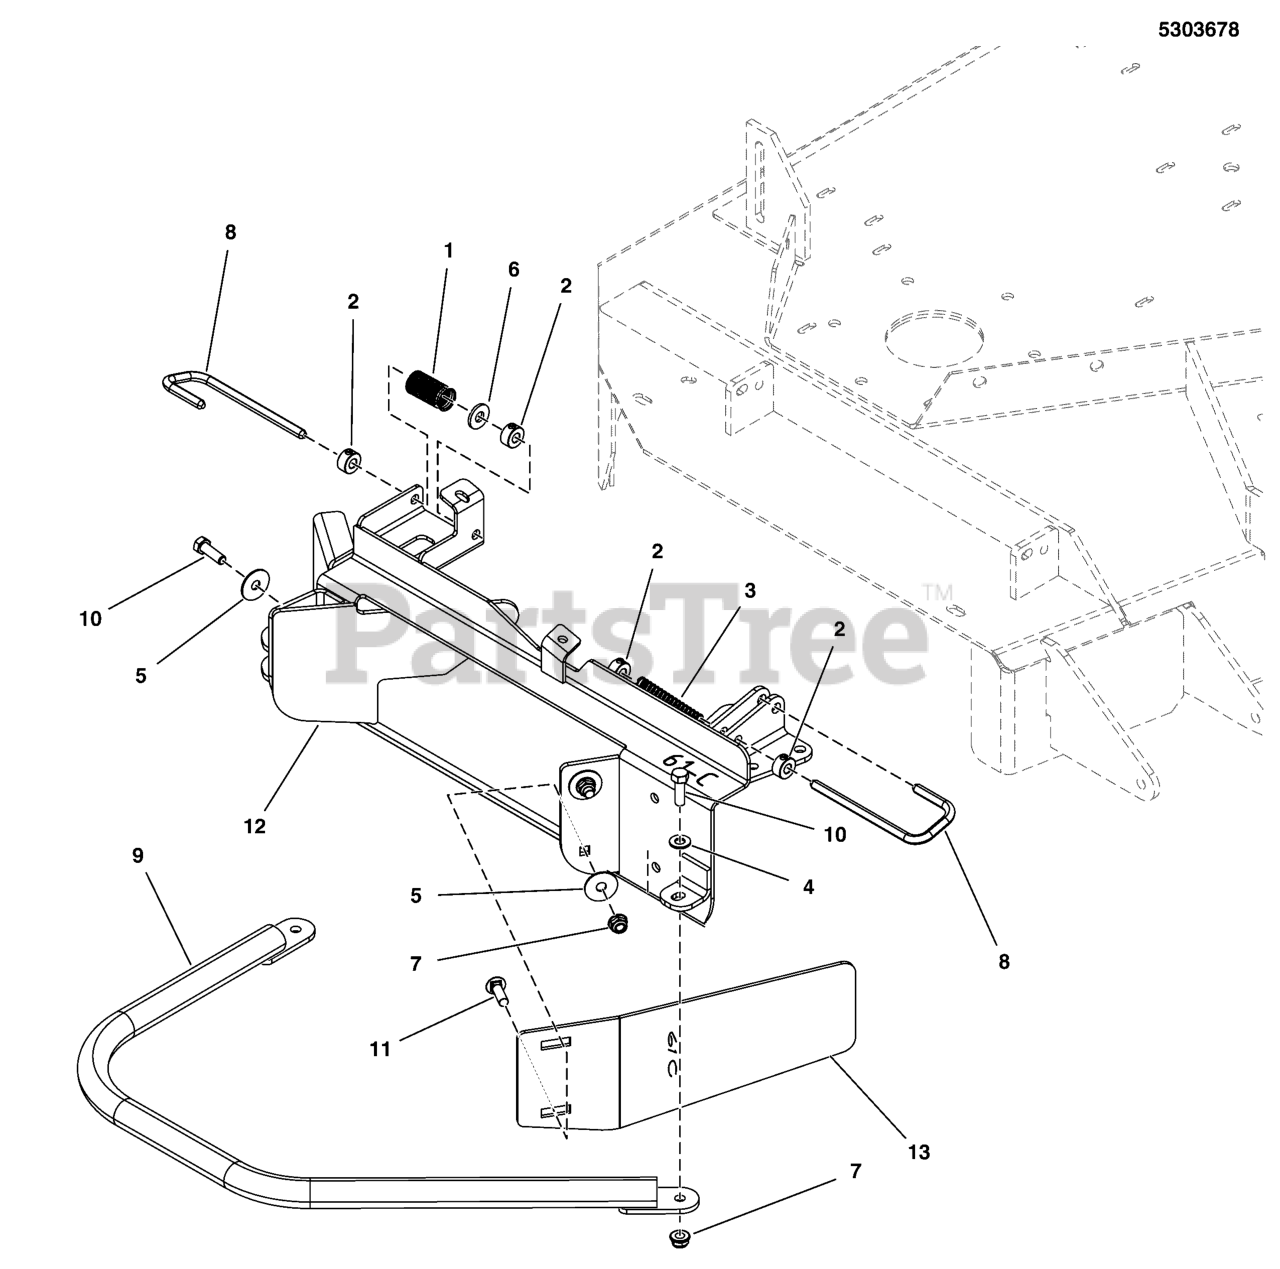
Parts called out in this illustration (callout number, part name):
1	SPRING-COMP 0.880ODX 02.187LG .062WIRE
2	COLLAR, 5/16 SET
3	SPRING-COMP, .375IDX2.75LGX.054WR, SS
4	WASHER, 5/16" SAE
5	WASHER, 5/16 FENDER
6	WASHER, 5/16 USS
7	NUT, 5/16-18 HEX NYLOCK FLANGE
8	ROD, LOCKING PIN, BLOWER
9	WELD, NERF BAR, 61" T-MAX - BLK
10	BOLT, 5/16-18 X 1 GD5 CZ
11	BOLT, 5/16-18 X 1, CARRIAGE
12	WELD, ADAPTER, 61" COM - BLK
13	DECK WEDGE, 61", COMMERCIAL - BLK
